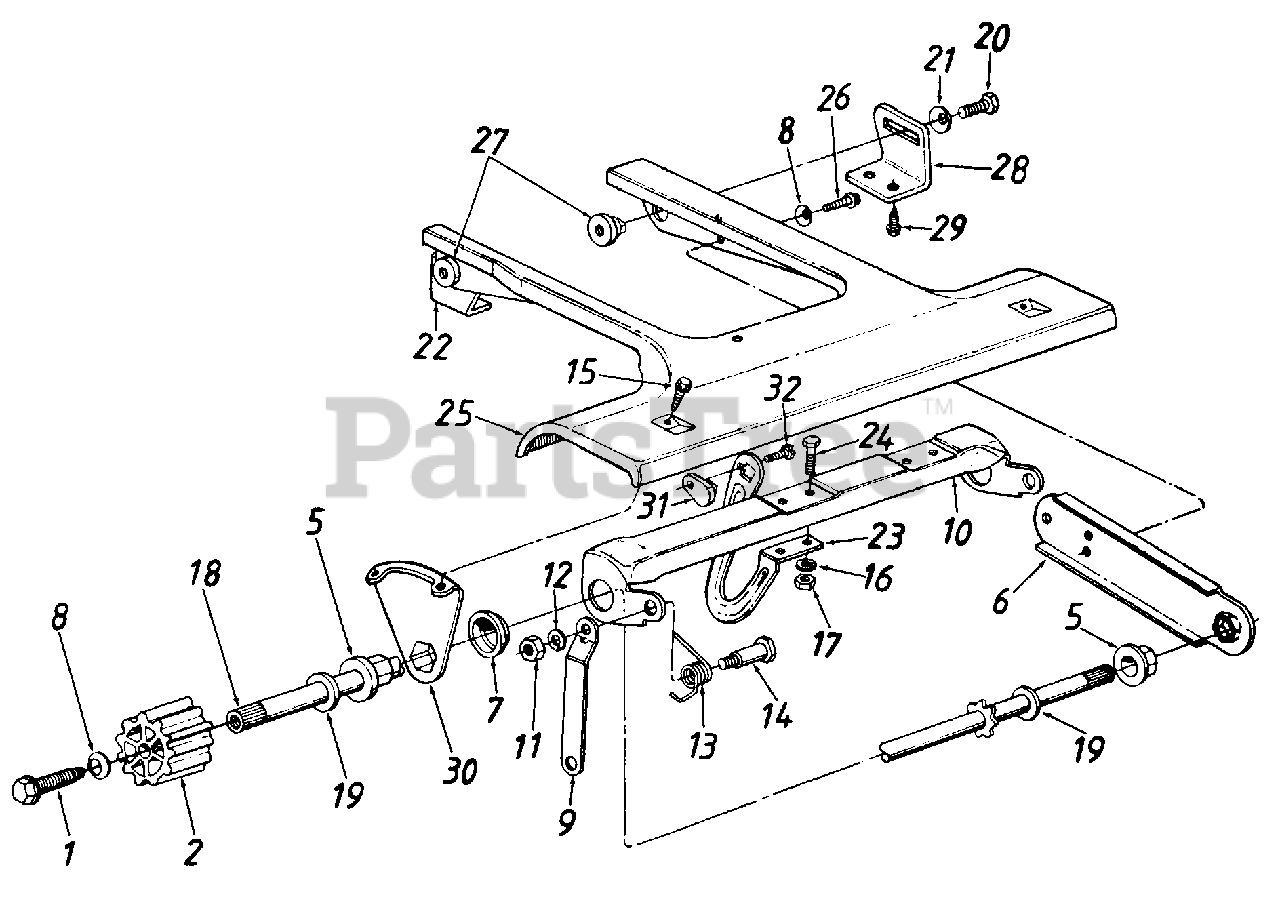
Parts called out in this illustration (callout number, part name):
1	Hex Wash. Hd. Tap Scr. 1/4-20 x .75" Lg.
2	Wheel Drive Pinion-Half
5	Hex Flange Brg. .504" I.D.
8	Bell-Wash. .265" I.D. x .75" O.D.
9	Link 5.06" Lg.
10	Drive Engagement Cam
11	Hex Nut 5/16-18 Thd.
12	L-Wash. 5/16" I.D.*
13	Torsion Spring-R.H.
14	Shoulder Bolt .437" Dia.
15	Hex AB-Tap Scr. 1/4" x .62" Lg.
16	L-Wash. 1/4" I.D.
17	Hex Nut 1/4-20 Thd.
18	Drive Shaft Ass'y.
19	Fl-Wash. .531" I.D. x .93" O.D.
20	Hex Bolt 5/16-18 x .62" Lg.
21	8ell-Wash. .345" I.D. x .88" O.D.
22	Pivot Bracket-R.H.
25	Front Pinion Pivot Cover
26	Hex B-Tap Scr. 1/4 x .38"
27	Shoulder Nut
28	Pivot Bracket-L.H.
29	Hex Wash. Hd. AB-Tap Scr. 1/4 x.62" Lg.
32	Hex B-Tap Scr. #10 x .44" Lg.
